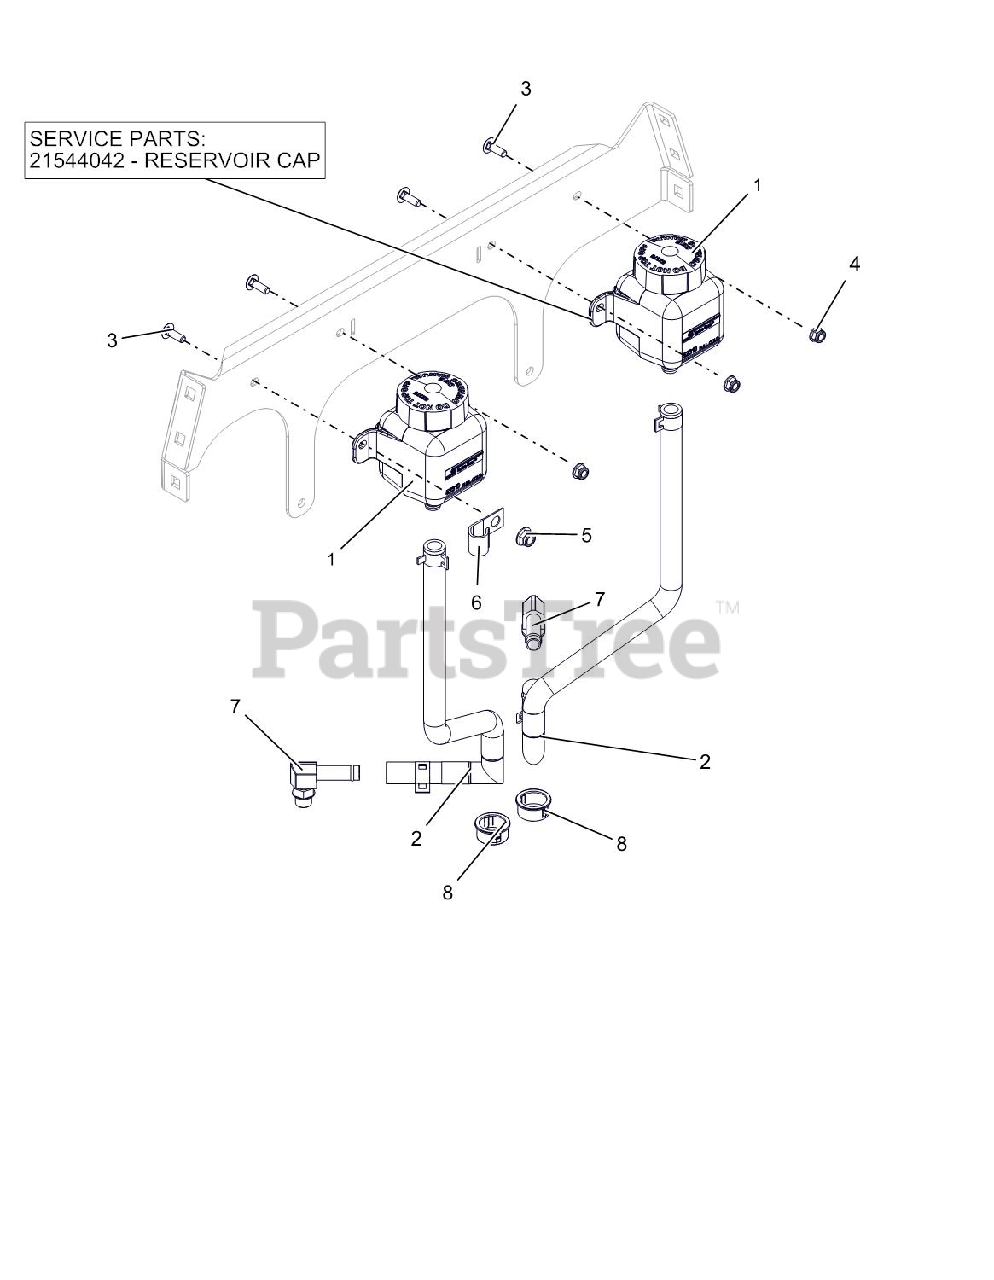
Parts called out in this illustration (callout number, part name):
1	TANK, EXPANSION
1	CAP, HYDRO RESERVOIR REPLAC.
2	HYDRO, SYSTEM PRO-STANCE
3	@BLT-RDHDSQNK .25-20X.75 G5YZ
4	@NUT-LK-NYL-FLG .25-20 YWZC
5	@NUT-LK-NYL-FLG .31-18 YWZC
7	FITTING, HYD (90 DEG)
8	BSHG, PANEL SNAP .937X1.11X.56
